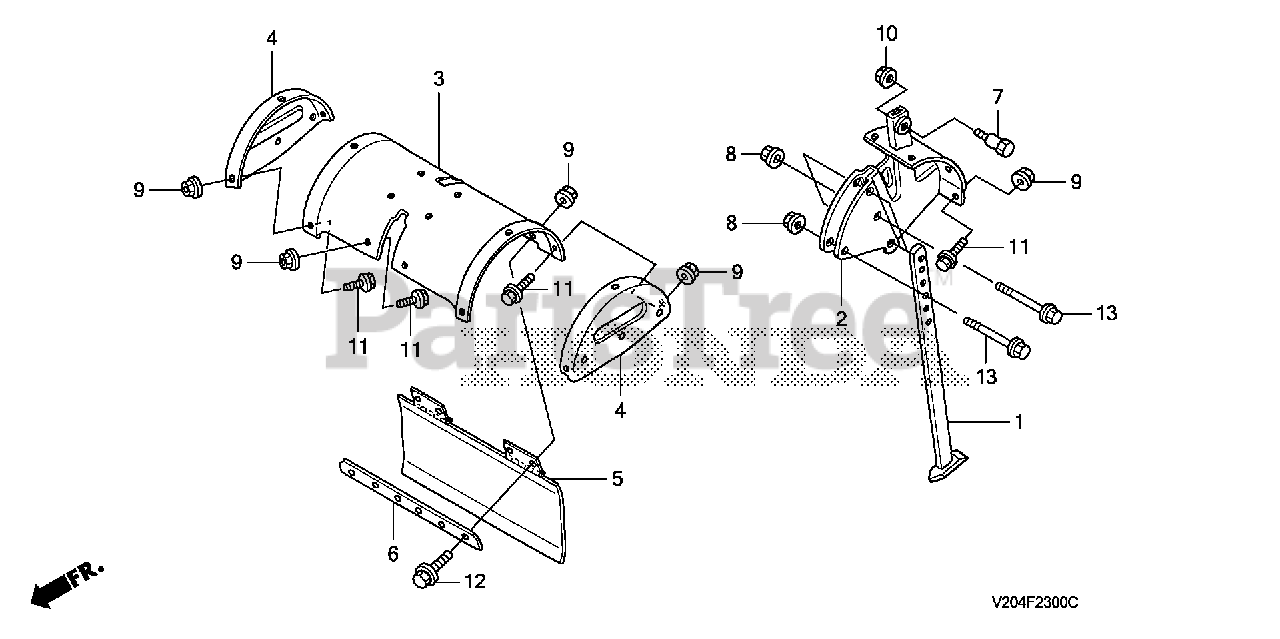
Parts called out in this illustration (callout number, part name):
1	BAR, DRAG *NH105* (MAT BLACK)
2	HOLDER, DRAG BAR *R280* (POWER RED)
3	COVER, ROTARY MAIN *R280* (POWER RED)
4	COVER, ROTARY SIDE *R280* (POWER RED)
5	SPLASH GUARD, ROTARY CENTER *NH105* (MAT BLACK)
6	STAY, SPLASH GUARD *NH105* (MAT BLACK)
7	BOLT, DRAG BAR
8	NUT, SELF-LOCK (10MM)
9	NUT, FLANGE (8MM)
10	NUT, FLANGE (8MM)
11	BOLT, FLANGE (8X16)
12	BOLT, FLANGE (8X18)
13	BOLT, FLANGE (10X55)
